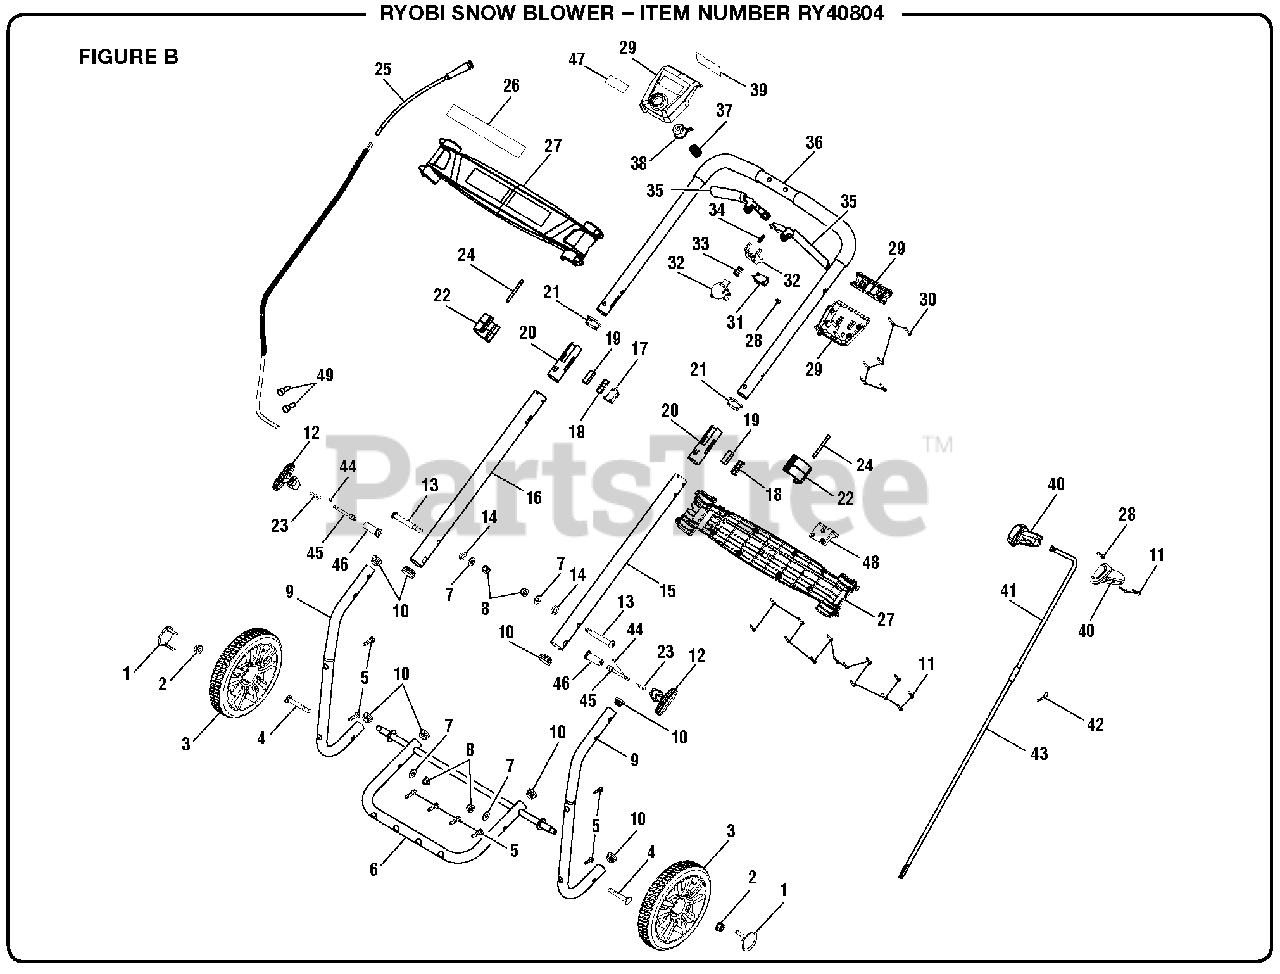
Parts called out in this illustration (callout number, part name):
1	Wheel Cover (Light Grey)
2	Lock Nut (3/8-16)
3	8 in. Wheel Assembly
4	Screw (M8 x 60 mm, Special Hd.)
5	Screw (1/4-15, T30 Torx Pan Hd.)
6	Lower Support Tube and Axle Assembly
7	Washer (ID8.5 x OD20.5 x 2 mm x 2t)
8	Flange Lock Nut (M8 x 1.25 mm)
9	Lower Handle
10	End Cap Set (22 mm)
11	Screw (4 x 18 mm, T15 Torx Pan Hd.)
12	Spring Pin Adjustment Knob
13	Screw (M8 x 73 mm, T40 Torx Button Hd.)
14	Block Washer (ID10.4 x OD22 x 6.75t)
15	Left Middle Straight Tube
16	Right Middle Straight Tube
18	Locking Block
19	Rubber Gasket
20	Handle Tube Bushing
21	Straight Tube Bushing
22	Telescoping Latch
23	Compression Spring
25	Wiring Assembly
26	Mid Panel Logo Label
27	Mid Trim Housing Assembly
28	Screw (M4 x 10 mm, T20 Torx Pan Hd.)
29	Trigger Housing Assembly
30	Screw (M4 x 30 mm, T15 Torx Soc. Hd.)
31	On/Off Switch
32	Switch Button Assembly
33	Compression Spring (Trigger Handle)
34	Compression Spring (Trigger)
35	Trigger Assembly
36	Upper Handle Assembly
37	Compression Spring
38	Safety Button
39	Start Label
40	Chute Handle Assembly
41	Upper Rod
42	Hitch Pin
43	Lower Rod
44	Spring Pin
45	Detent Pin
46	Spring Pin Housing
47	Logo Label
48	Chute Support (Plastic)
49	Wire Connector
